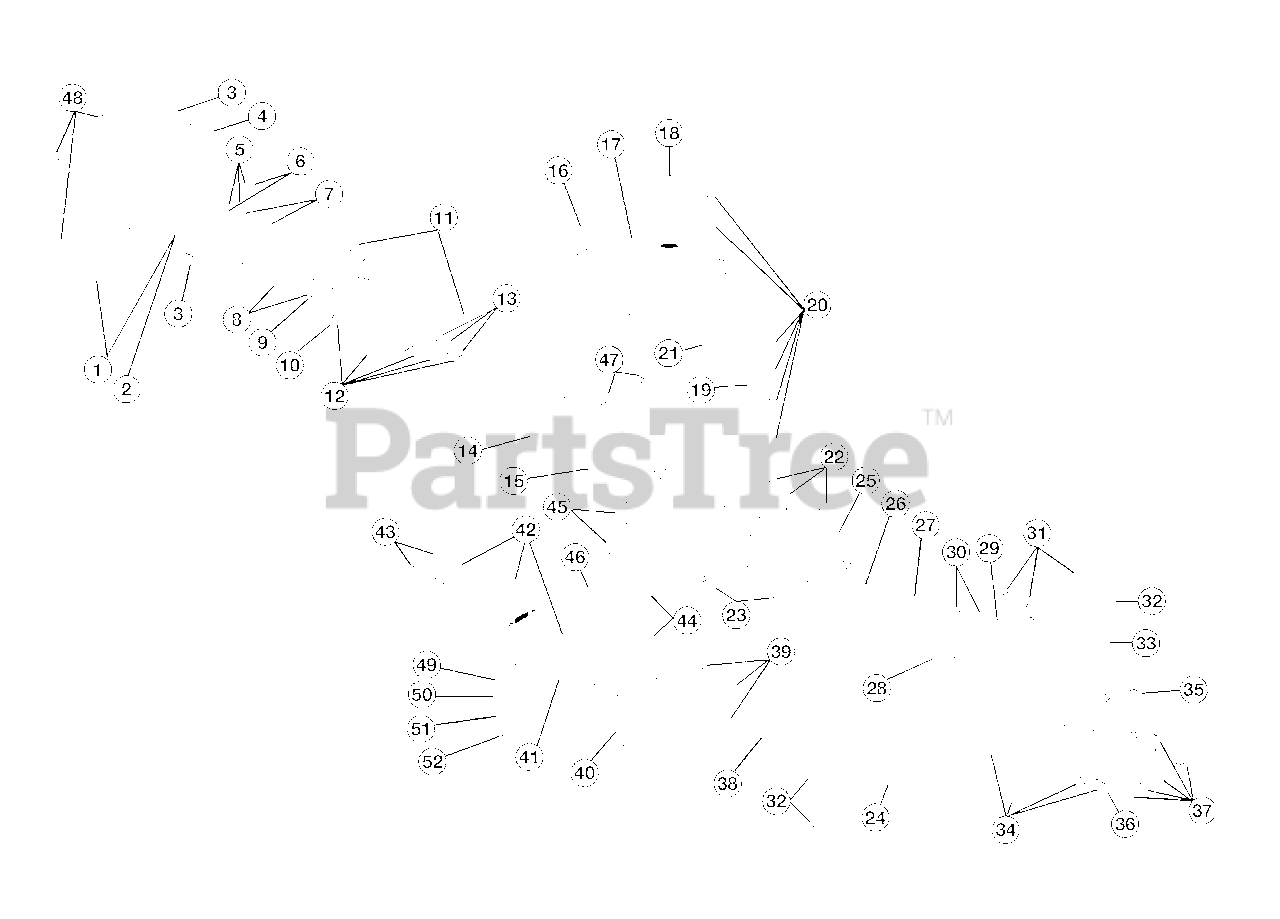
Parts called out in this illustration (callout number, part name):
1	Air Cleaner/Muffler Cover Assembly
2	Air Cleaner Filter
3	Carburetor Mounting Screw Assembly
4	Wavey Washer
5	Choke Lever Assembly
6	Choke Knob and Screw
7	Choke Lever and Plate
8	Carburetor Assembly
9	Carburetor Gasket
10	Carb Mount Screw
11	Primer and Hose Assembly
12	Carb Mount Assembly
13	Reed Assembly
14	Carburetor Mount Gasket
15	Crank Case Service Assembly
16	Rear Mounting Pad
17	Fuel Tank Assembly
18	Fuel Cap Assembly
19	Fuel Return Line
20	Fuel Line Assembly
21	Front Mounting Pad
22	Shroud Assembly
23	Shroud Screw
24	Shroud Extension and Stand
25	Flywheel Assembly
26	Square Nut Drive
27	Recoil Pulley Assembly
28	Recoil Spring
29	Rope Guide
30	Pulley Retainer Assembly
31	Switch Assembly
32	Pull Handle
34	Starter Housing Assembly
35	Housing Screw
36	Cover Screw
37	Upper Clamp Assembly
38	Wire Lead
39	Module Assembly
40	Spark Plug
41	Exhaust Gasket
42	Muffler Assembly
43	Muffler Mounting Bolt Assembly
44	Cylinder Assembly
45	Piston and Rod Assembly
46	Cylinder Gasket
47	Cylinder Bolt
48	Cover Screw
49	Spark Arrestor
50	Inner Hood
51	Hood
52	Screw
